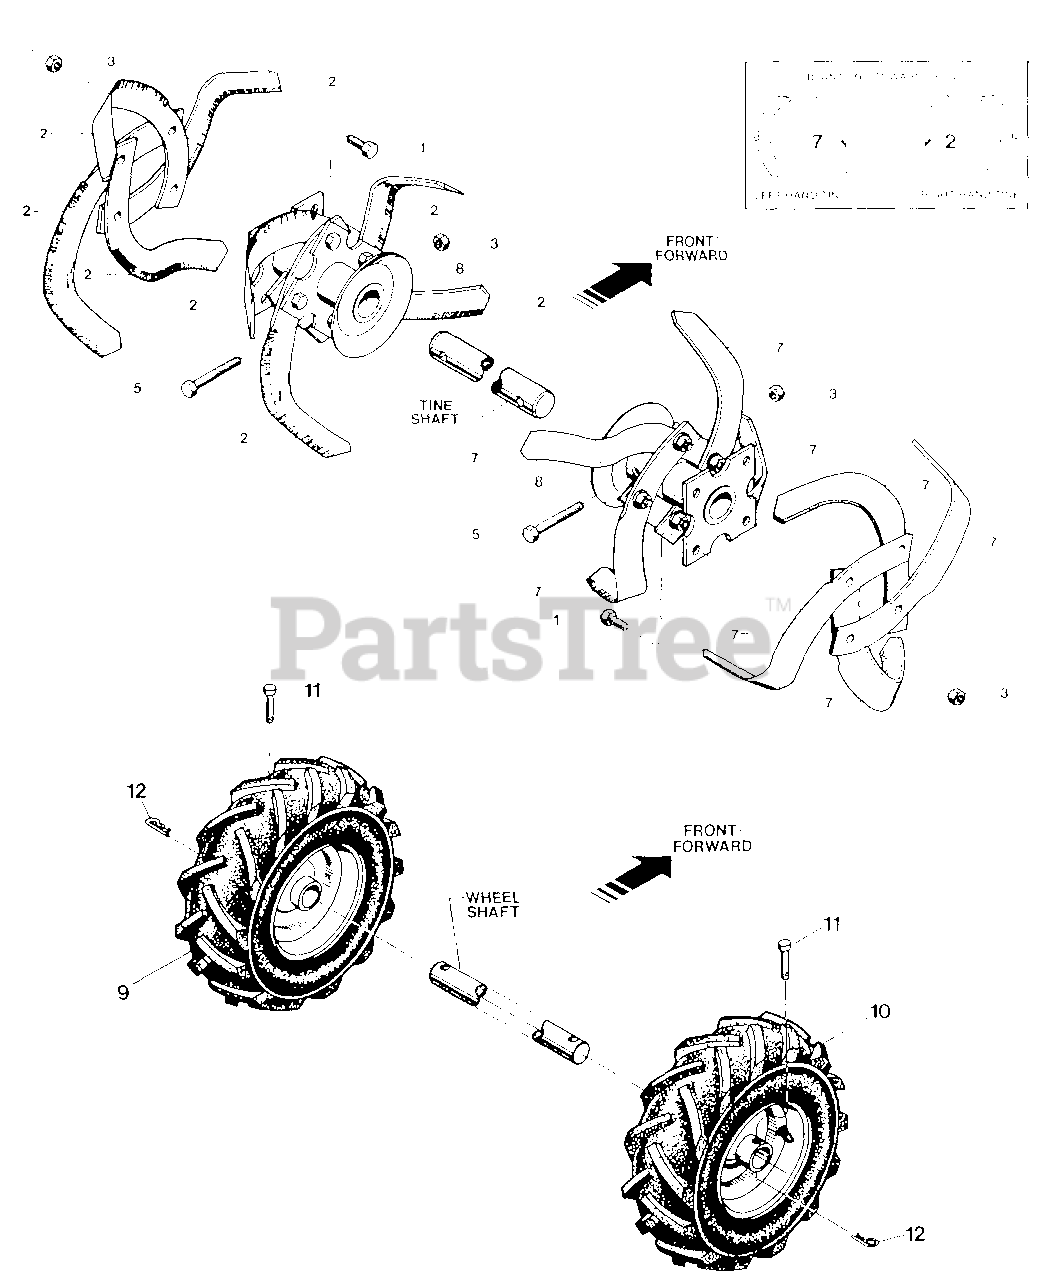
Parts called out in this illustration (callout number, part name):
1	Screw-hex hd., 3/8-16 x 1-1/4"
2	Bolo Tine-single, right hand tine used on left side of tiller
3	Hex Locknut, 3/8-16
5	Screw-hex hd., 3/8-16 x 2, GRADE 8
7	Bolo Tine-single, left hand tine used on right side of tiller
8	Tine Holder-for bolo tines, left and right sides
9	Wheel & Tire Assy-left side,
10	Wheel & Tire Assy-right side, same specs. as above
11	Clevis Pin- 312 x 1-3/4 long
12	Hitch Pin
